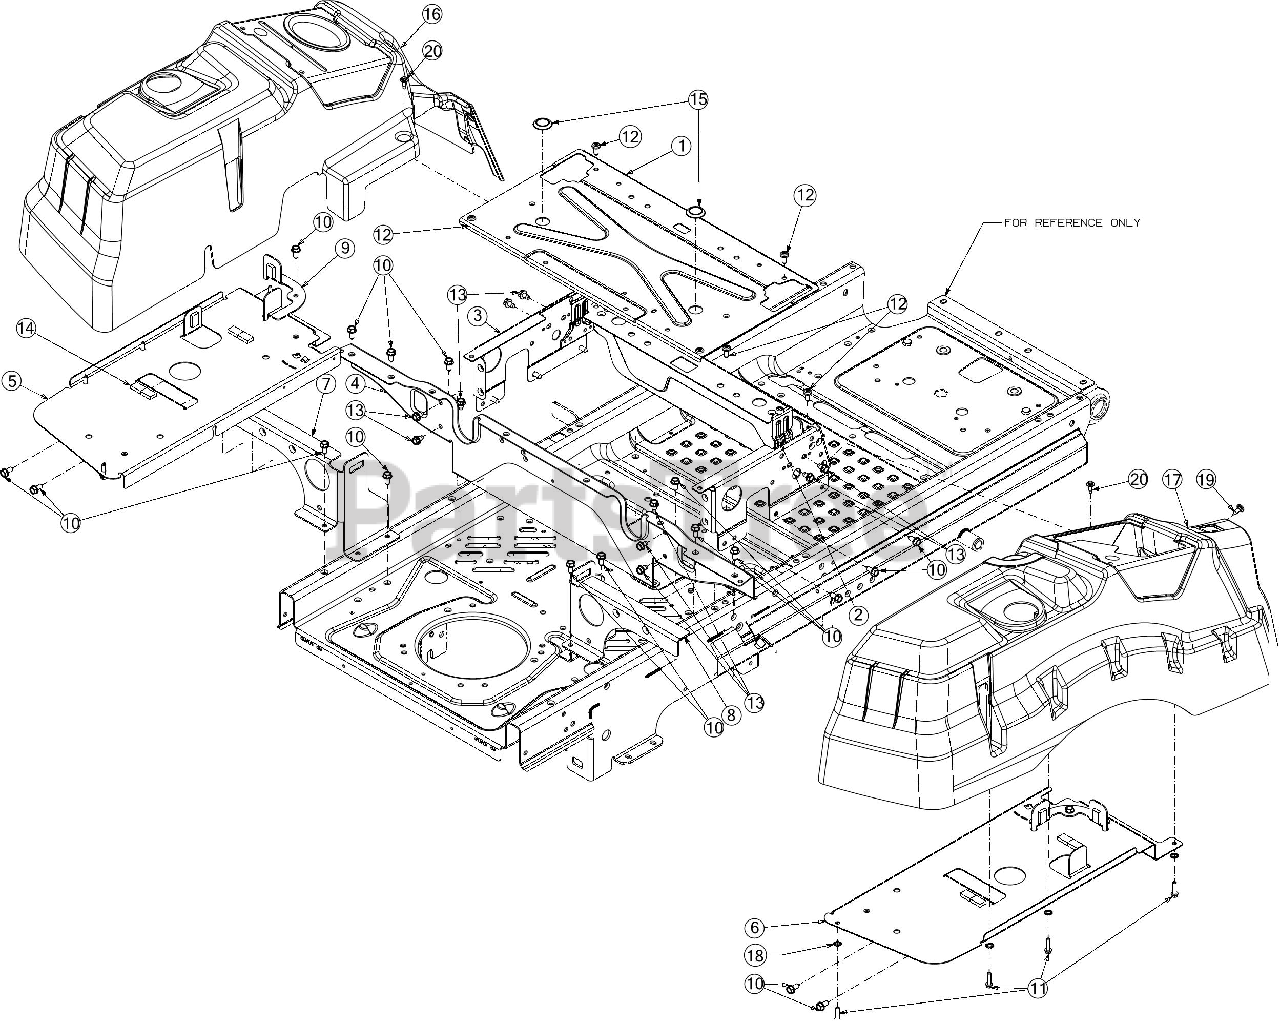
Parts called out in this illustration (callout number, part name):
1	SEATBOX TOP PLATE
2	LAPBAR BRACE BRACKET
3	SEAT FRAME
4	REAR SEATBOX BRACE
5	TANK SUPPORT PLATE (LH)
6	TANK SUPPORT PLATE (RH)
7	REAR BRACKET SUPPORT (LH)
8	REAR BRACKET SUPPORT (RH)
9	REAR TANK BRACKET
10	SCREW 5/16-18 x .750
11	SCREW 5/16-14 x 1
12	SCREW 5/16-18 x .750
13	SCREW 5/16-18 x .500
14	FOAM TAPE .625 WIDE x .25 THK BULK
16	CONSOLE (LH) 2.25" CAP
17	CONSOLE (RH) 2.25" CAP
19	TORX SHOULDER SCREW 1/4-20
20	SHOULDER SCREW M6-1 .368 X.115
